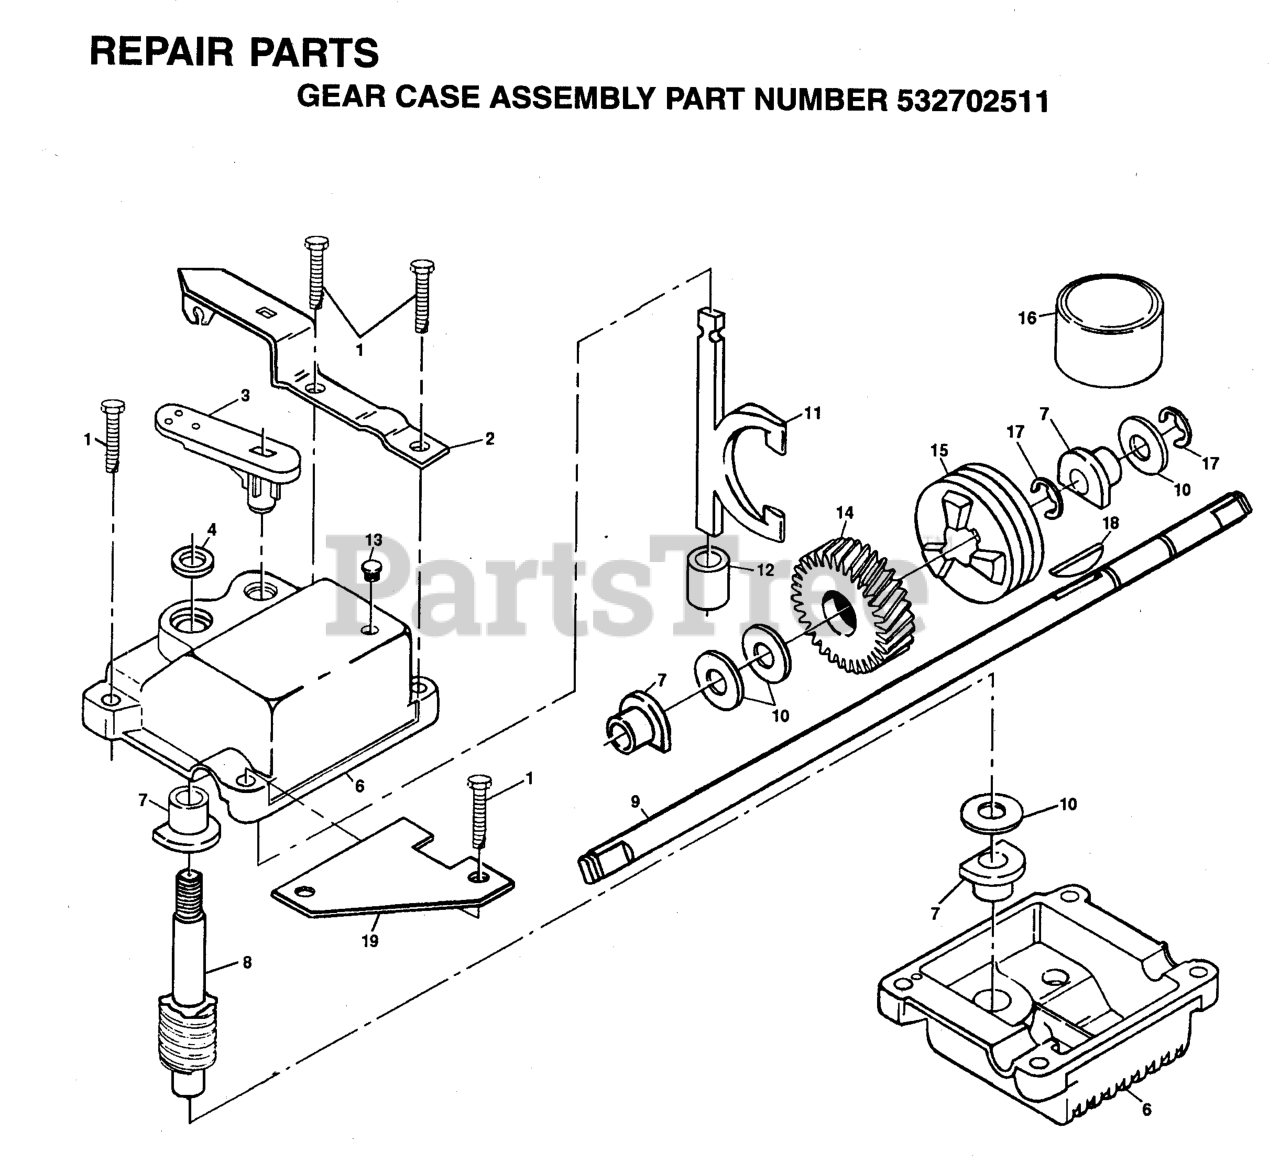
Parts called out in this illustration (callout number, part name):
1	SCREW
2	BRACKET
8	WORM SHAFT
9	DRIVE SHAFT, 20-5/8"
10	THRUST WASHER
11	YOKE.VIBRATORY FINISH.
13	PLUG.AUGER.GEAR.BOX.SNOW
14	GEAR.HELICAL
15	CLUTCH JAW
16	GREASE
18	HI PRO KEY
19	BRACKET SPRING
